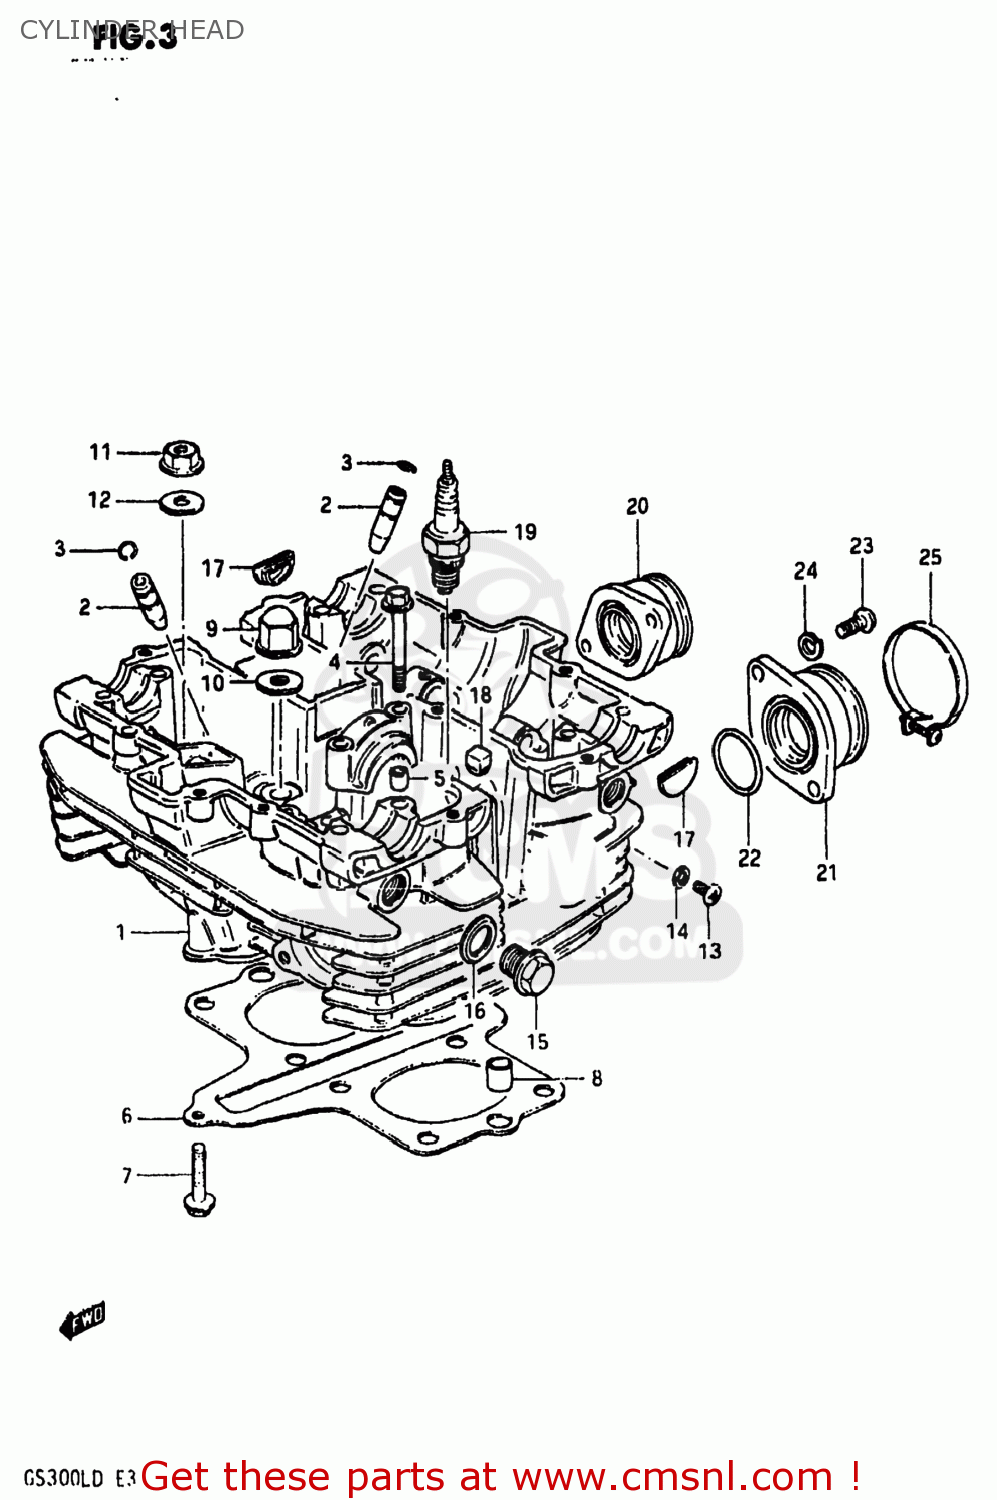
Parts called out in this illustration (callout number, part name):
1	HEAD ASSEMBLY,CYLINDER
2	GUIDE,INTAKE VALVE
3	RING,SNAP
4	BOLT(6X39)
5	PIN(6.2X8X11)
6	GASKET,CYLINDER HEAD (NAS)
7	BOLT
8	PIN
9	NUT
10	GASKET(8.5X20X2.3) (NAS)
11	NUT
12	WASHER(8.5X19X2.3)
13	SCREW
14	GASKET(5.3X9.3X1.2) (NAS)
15	PLUG (14X12)
16	GASKET(14X19.2X2) (NAS)
17	PLUG
18	PAD,CYLINDER HEAD
19	SPARK PLUG D9EA
20	PIPE,INTAKE,R
21	PIPE,INTAKE,L
22	O-RING (D:2.4 ID:29.7)
23	SCREW
24	LOCK WASHER
25	CLAMP
